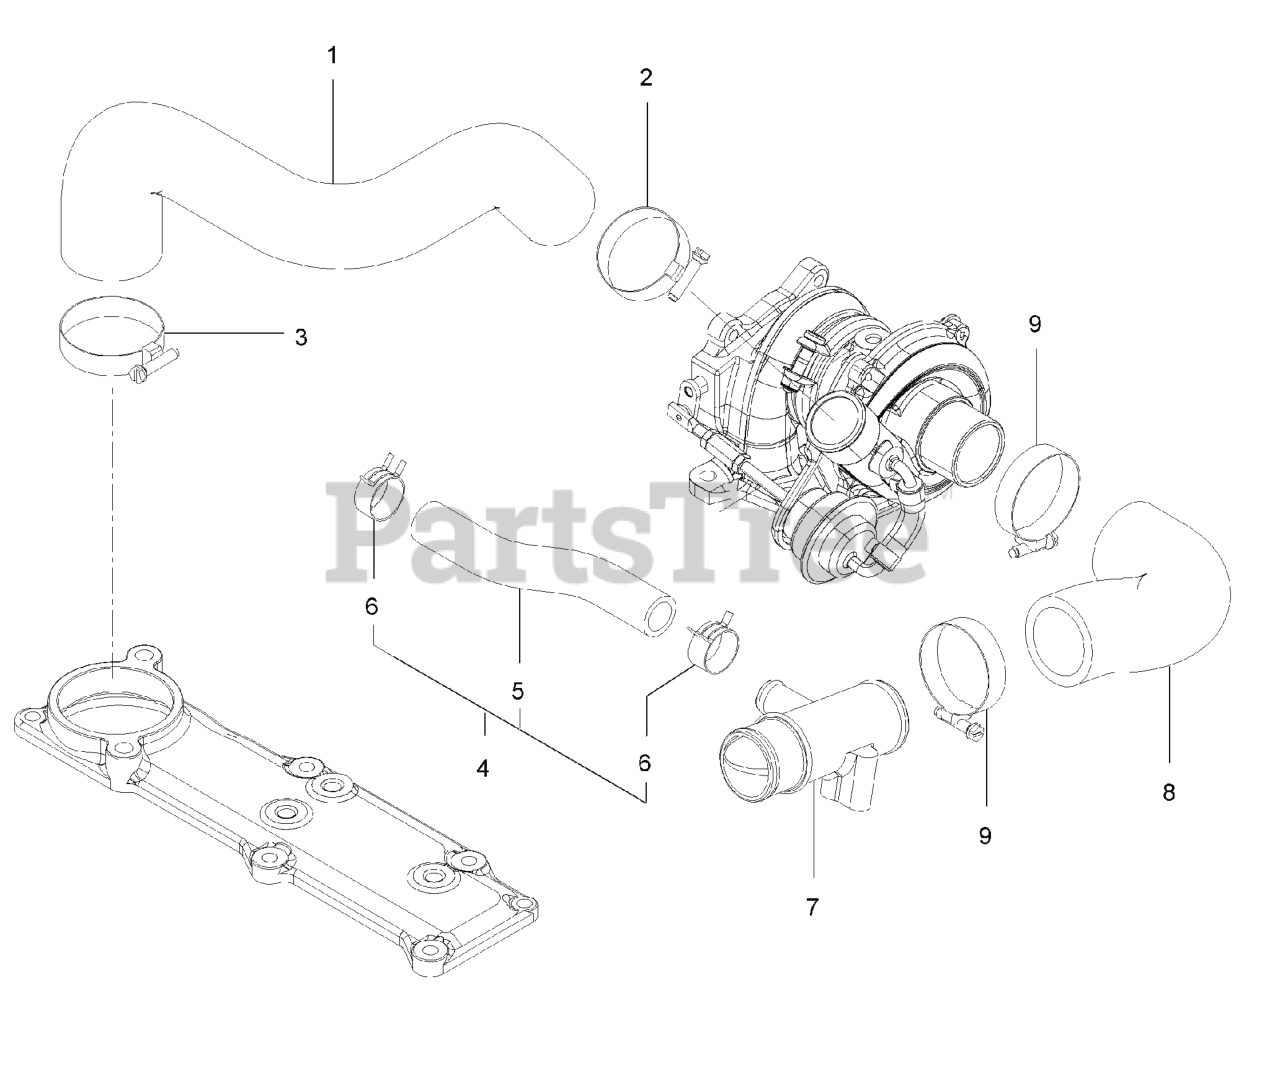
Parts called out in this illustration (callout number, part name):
1	HOSE-AIR INTAKE
2	CLAMP-HOSE
3	CLAMP-HOSE
4	HOSE ASM-BREATHER
5	Hose-Breather
6	CLIP-HOSE
7	JOINT-BREATHER
8	HOSE-AIR INTAKE
9	CLAMP-HOSE
